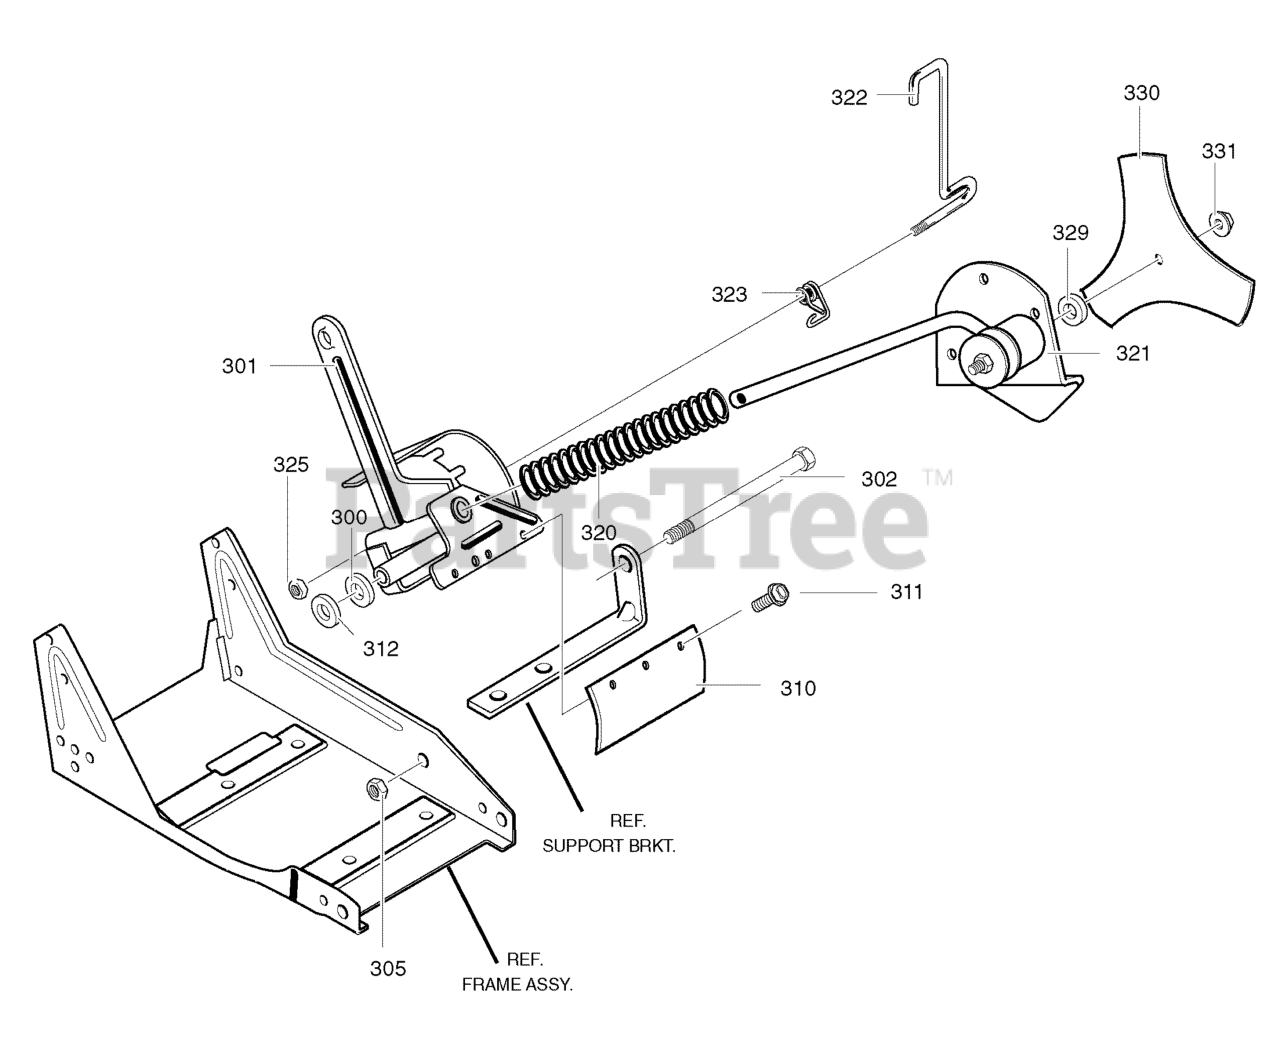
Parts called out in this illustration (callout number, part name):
300	FLATWASHER
301	QUILL, Support
302	BOLT, 3/8-16
305	NUT, 3/8-16
310	DEFLECTOR, Rubber
311	SCREW 10-16x1.50
312	FLATWASHER
320	SPRING, Compression
321	QUILL, Assembly
322	LEVER, Index
323	SPRING, Torsion
325	NUT, 5/16-18
329	FLATWASHER
330	BLADE, Edger
331	NUT, 1/2-20
